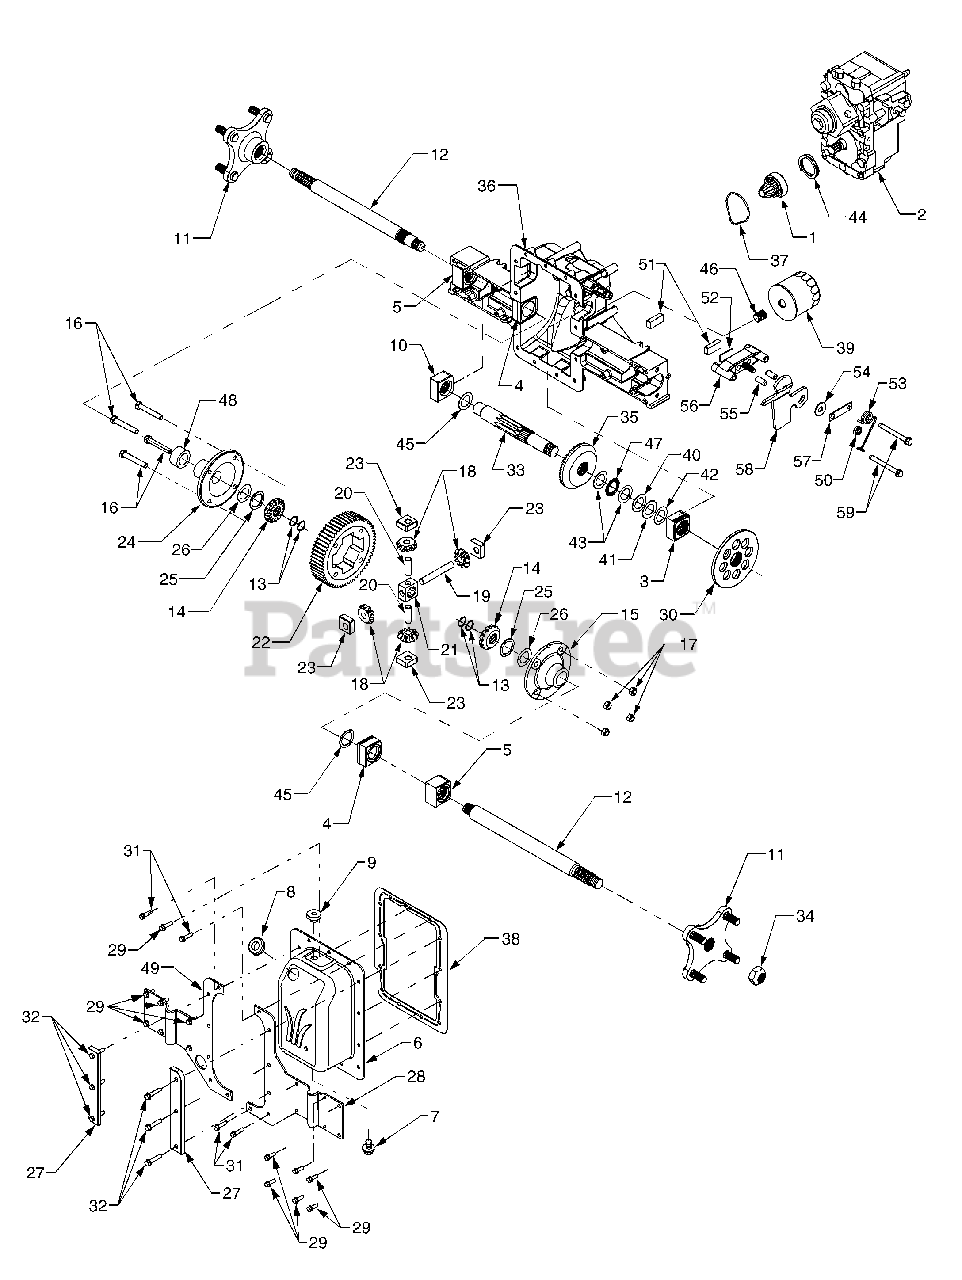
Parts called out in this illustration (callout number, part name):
1	Gear Assembly, Pinion 13T
2	Hydrostatic Transmission Assy. Kit
3	Bearing Block Assembly, Needle
4	Bearing Block Assembly
5	Bearing Block Assembly
6	Cover Assembly, Rear
7	Plug, Drain, M14 x 1.5 x .827
8	Grommet, Rubber
10	Bearing Block Assembly
11	Hub Assembly, Wheel
12	Axle Shaft,
13	Retaining Ring
14	Gear, Spur, 14T
15	Housing, Diff. Cover RH
16	Hex Cap Screw, 3/8-24 x 2.25 GR5
17	Nut, Hex Lock, 3/8-24
18	Gear, Differential 10T
19	Shaft, Cross, .5 x 3.485
20	Shaft, Cross, Special
21	Differential Pinion Block
22	Gear, Spur 60T
23	Block, Thrust Miter
24	Housing, Differential Cover LH
25	Washer, Flat, 1.0 x 1.56 x .040
26	Washer, Flat, 1.0 x 1.56 x .020
27	Block, Transmission Cover
28	Plate, Trans. Support RH
29	Screw, Hex Wash. Hd. Tapp 1/4-20 x .75
30	Disc, Brake
31	Screw, Hex Wash. Hd. Tapp 1/4-20 x 1.0
32	Screw, Hex Wash. Hd. Tapp 1/4-20 x 1.25
33	Shaft, Output 9T
34	Nut, Lock, 3/4-16
35	Gear, Bevel 54T
36	Housing, Differential
37	O-Ring, 2.75 x .103
38	Gasket
39	Filter, Oil
40	Washer, Flat Shim, 1.0 x 1.56 x .010
41	Washer, Flat Shim, 1.0 x 1.56 x .020
42	Washer, Flat Shim, 1.0 x 1.56 x .015
43	Washer, Thrust, 1.007 x 1.542 x .03
44	Washer, Spring
45	Washer, Flat, 1.01 x 1.86 x .060
46	Fitting, Filter Nipple
47	Bearing, Needle Thrust
48	Spacer, Axle, 1.0 x 1.665 x .71
49	Plate, Trans. Support LH
50	Nut, Hex Insert Lock, 5/16-24
51	Pad, Brake
52	Plate, Puck
53	Spring, Torsion
54	Washer, Flat, .343 x .88 x .062
55	Pin, Brake Actuator
56	Yoke, Brake
57	Bracket, Brake Anti-Rotation
58	Arm, Brake Actuator
59	Screw, Hex Wash. Hd. Tapp 1/4-20 x 2.375
